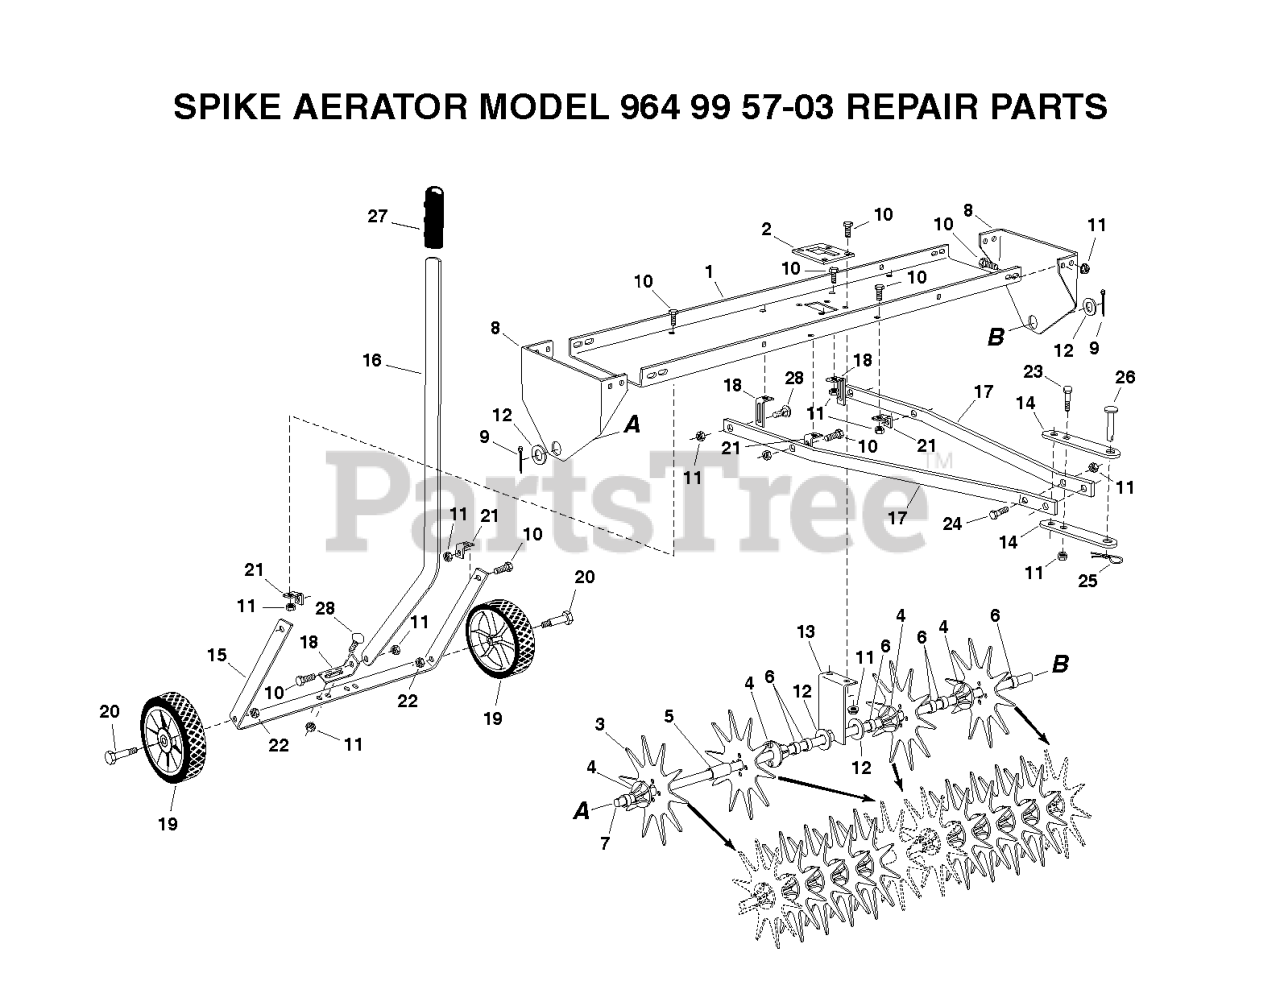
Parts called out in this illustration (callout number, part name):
14	BRACKET THATCHER
23	Bolt Fin Hex 5/16 - 18 Unc x 2 Gr. 2
27	Rubber Grip
